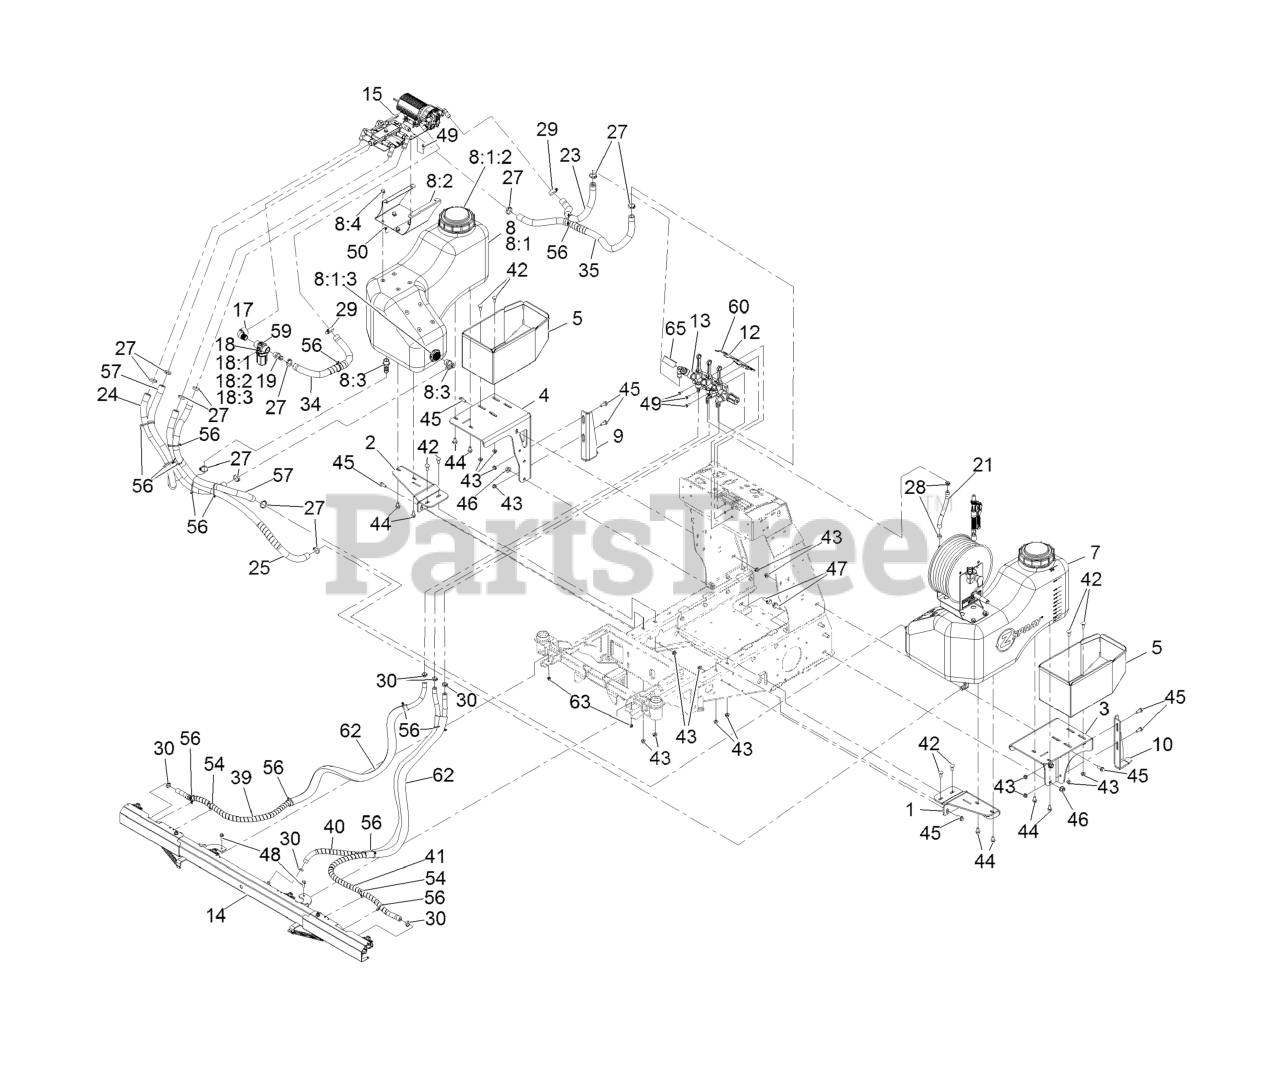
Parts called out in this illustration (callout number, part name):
1	Mount-Tank, LH Wing
2	Mount-Tank, RH Wing
3	Mount-Box, Lt Fert
4	Mount-Box, Rt Fert
5	BOX-FERT
7	ASM-Tank, Hose Reel
8	ASM-Tank, Rt
8:1	ASM-TANK, RT
8:1:2	CAP-TANK, SPRAY
8:1:3	FITTING-BULKHEAD
8:2	FITTING-ELBOW, 90
8:3	PLATFORM, LIQUID VALVE MO
8:4	Screw-HHF
9	Bracket-Anti-Tip, Rt
10	Bracket-Anti-Tip, Lt
12	Bracket-Manifold
13	ASM-Manifold
14	ASM-Boom, Spray
15	ASM, Liquid Valve
17	ELBOW-90DEG
18	STRAINER-INLINE
18:1	BOWL-STRAINER
18:2	GASKET-HEAD, LINE STRAINE
18:3	Screen-Strainer, 50 Mesh
19	HOSEBARB
21	Hose-Spray
23	Hose-Spray
24	Hose-Spray
25	Hose-Spray, Wrapped
27	Clamp-Oetiker, 167
28	CLAMP-OETIKER, 167
29	CLAMP-HOSE
30	CLAMP-OETIKER, 167
34	Hose-Spray, Wrapped
35	Hose-Spray, Wrapped
39	Hose-Spray, Wrapped
40	Hose-Spray, Wrapped
41	Hose-Spray, Wrapped
42	SCREW-CARR
43	Nut-Hex Flange
44	SCREW-HHF
45	SCREW-HHF
46	NUT-HEX FLANGE
47	SCREW-HHF
48	SCREW-HHF
49	Screw-HHF
50	Nut-Hex Flange
54	CLIP-TIE
56	TIE-CABLE
57	Hose-Spray
59	DECAL-CAP, STRAINER
60	Decal-Valve, Boom
62	Guard-Mesh
63	Nut-Hex Flange
65	GAUGE
